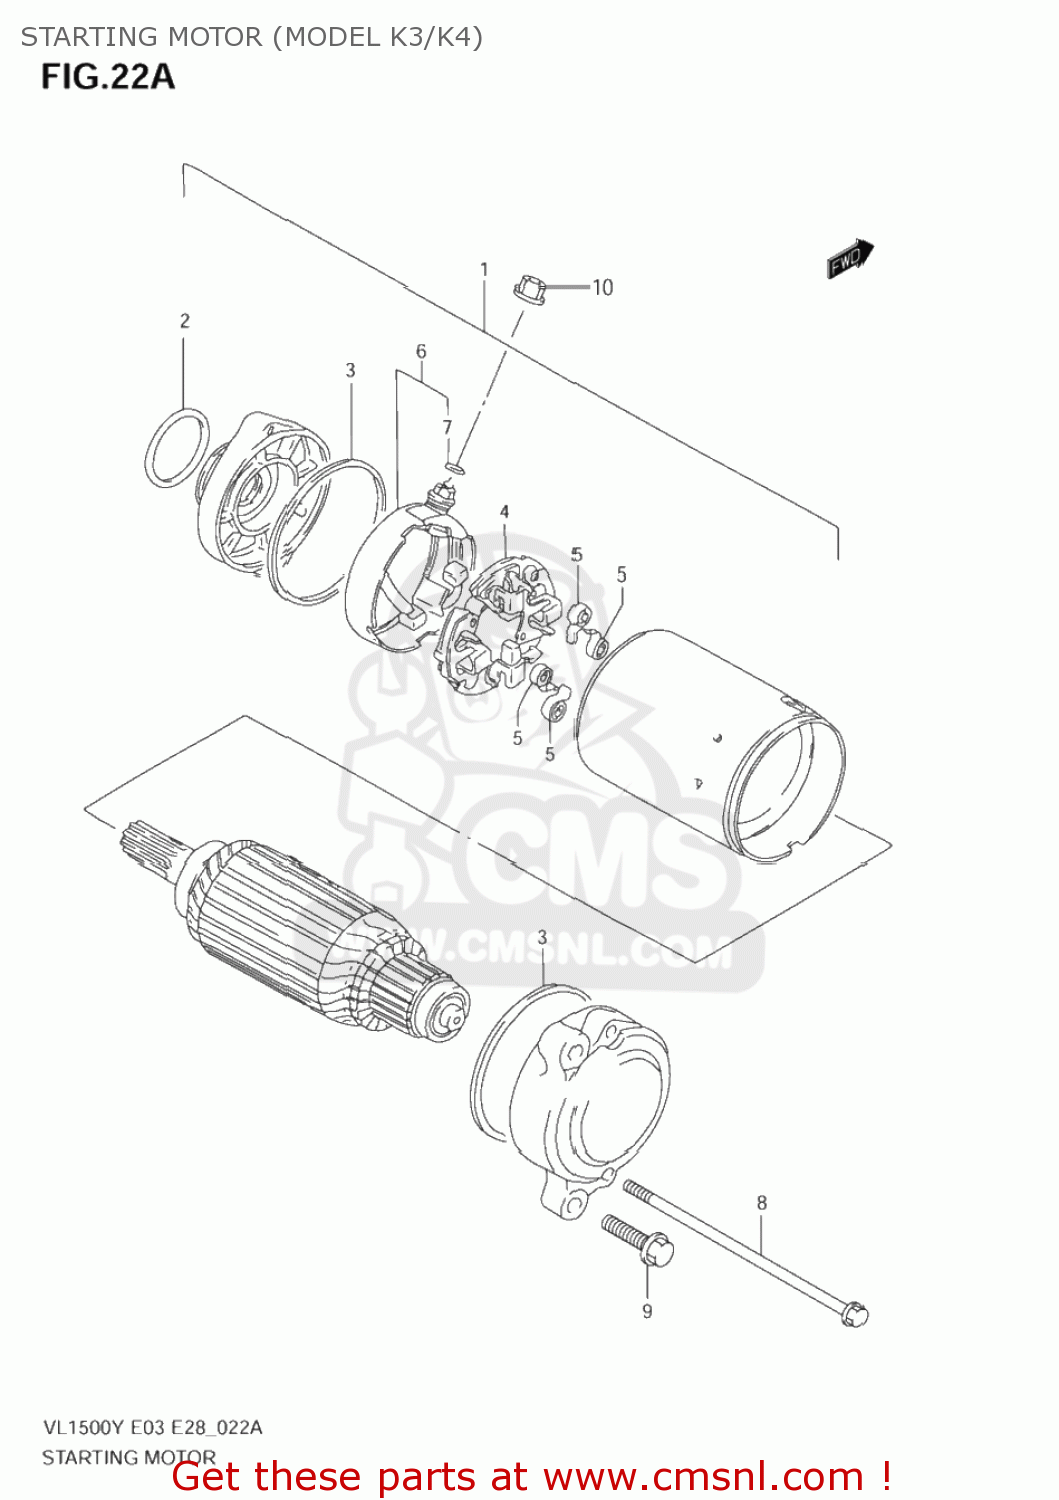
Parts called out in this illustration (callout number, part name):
1	MOTOR ASSY,STARTING
2	O-RING
3	O RING
4	HOLDER SET,BRUSH
5	SPRING,BRUSH
6	TERMINAL SET,BRUSH
7	O RING
8	BOLT
9	BOLT
10	NUT
